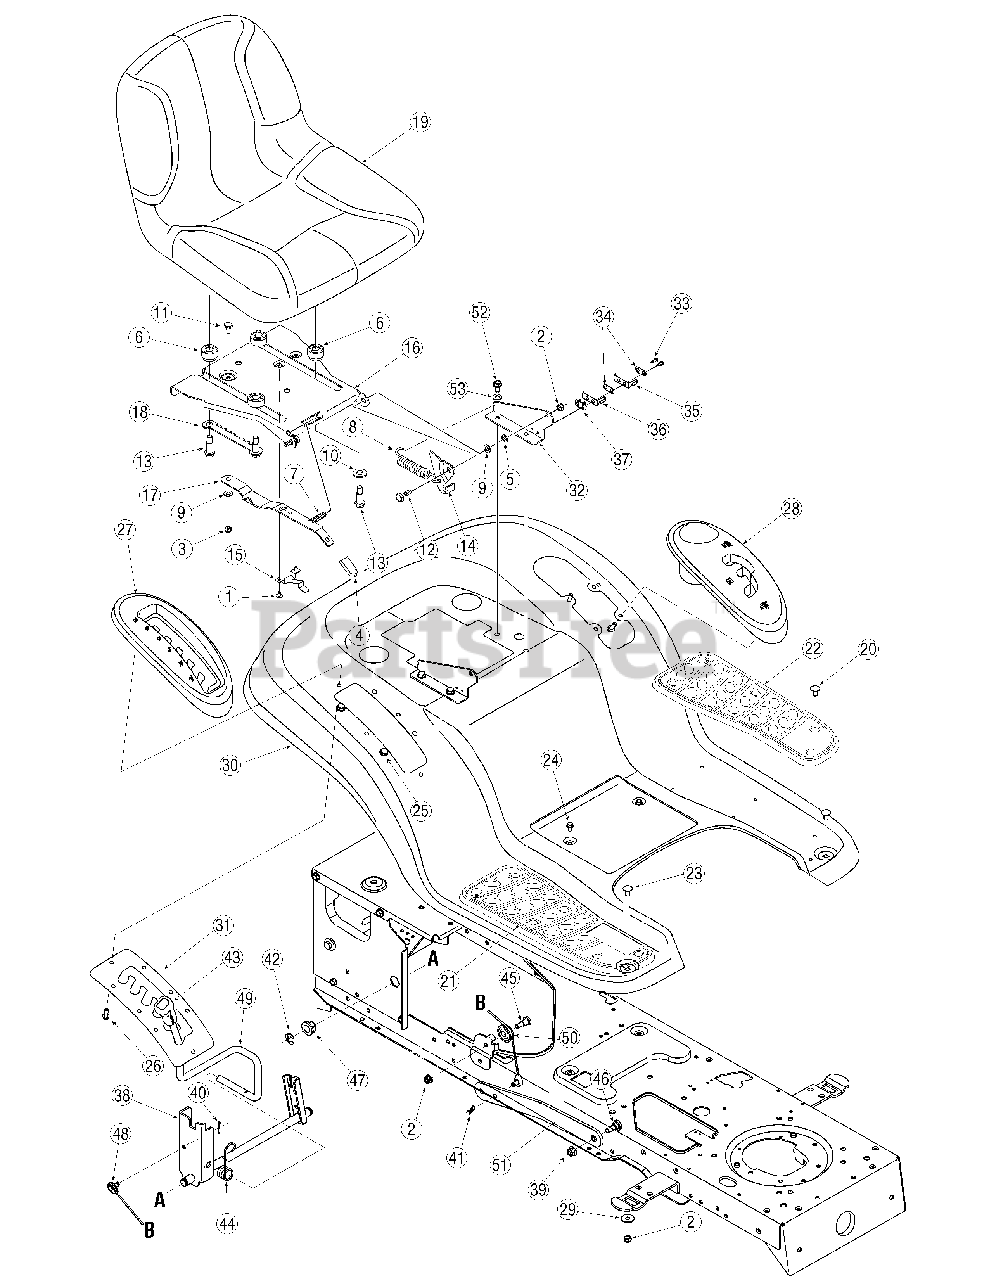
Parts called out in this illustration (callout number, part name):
1	Screw, #10-16 x .375
2	Nut, Flange Lock, 5/16-18, GrF
3	Nut, Flange Lock, 1/4-20
4	Seat Adjuster Grip
5	Nut, Speed, .3125 ID
7	Compression Spring, .41 x 1.5
8	Spring, Extension, .84 Dia. X 4.6
9	Wash, Flat, .344 x .688 x .065
10	Wash, Flat, .531x 1.062 x.1.34
11	Screw, Shoulder, .340 x .285
12	Screw, Shoulder, .437 x .268
13	Screw, Shoulder, .50 x .925
14	Seat Bracket, Lift
18	Seat Adjustment Selector
19	Medium Back Seat, Black
20	Ratchet Clip
21	RH Foot Pad, Rubber
22	LH Foot Pad, Rubber
23	Bolt, Carriage, 5/16-18, .750, Gr1
24	Screw, 1/4-20, 0.500
25	Screw, 5/16-12, 0.750
26	Screw, 1/4-15, 0.750
27	Cover, Lift Lever
28	Cover, w/ Cup Holder
29	Washer, Flat, .344 x 1.0 x .063
33	Screw, #8-18 x .50
34	Plate, Insulator
35	Spring Switch, Outer
36	Spring Switch, Inner
37	Plate, Insulator Boss
38	Shaft Assembly, Lift Service Kit
39	Nut, Flange Lock, 3/8-16,GrF
40	Pin, Cotter, .072 Dia. x 1.13
41	Pin, Cotter, 3/32, 1.0
42	Ring, E Type, .625 Dia.
43	Grip, Handle, 1/2
44	Spring, Torsion
45	Screw, 5/16-18 x .620 Gr2
46	Screw, Shoulder, .50 x .27
47	Bearing, Hex Flange
48	Cable, Lift, 16.16
50	Pulley, Roller
52	Screw, 5/16-18 x .625
53	Lock Washer, 5/16
